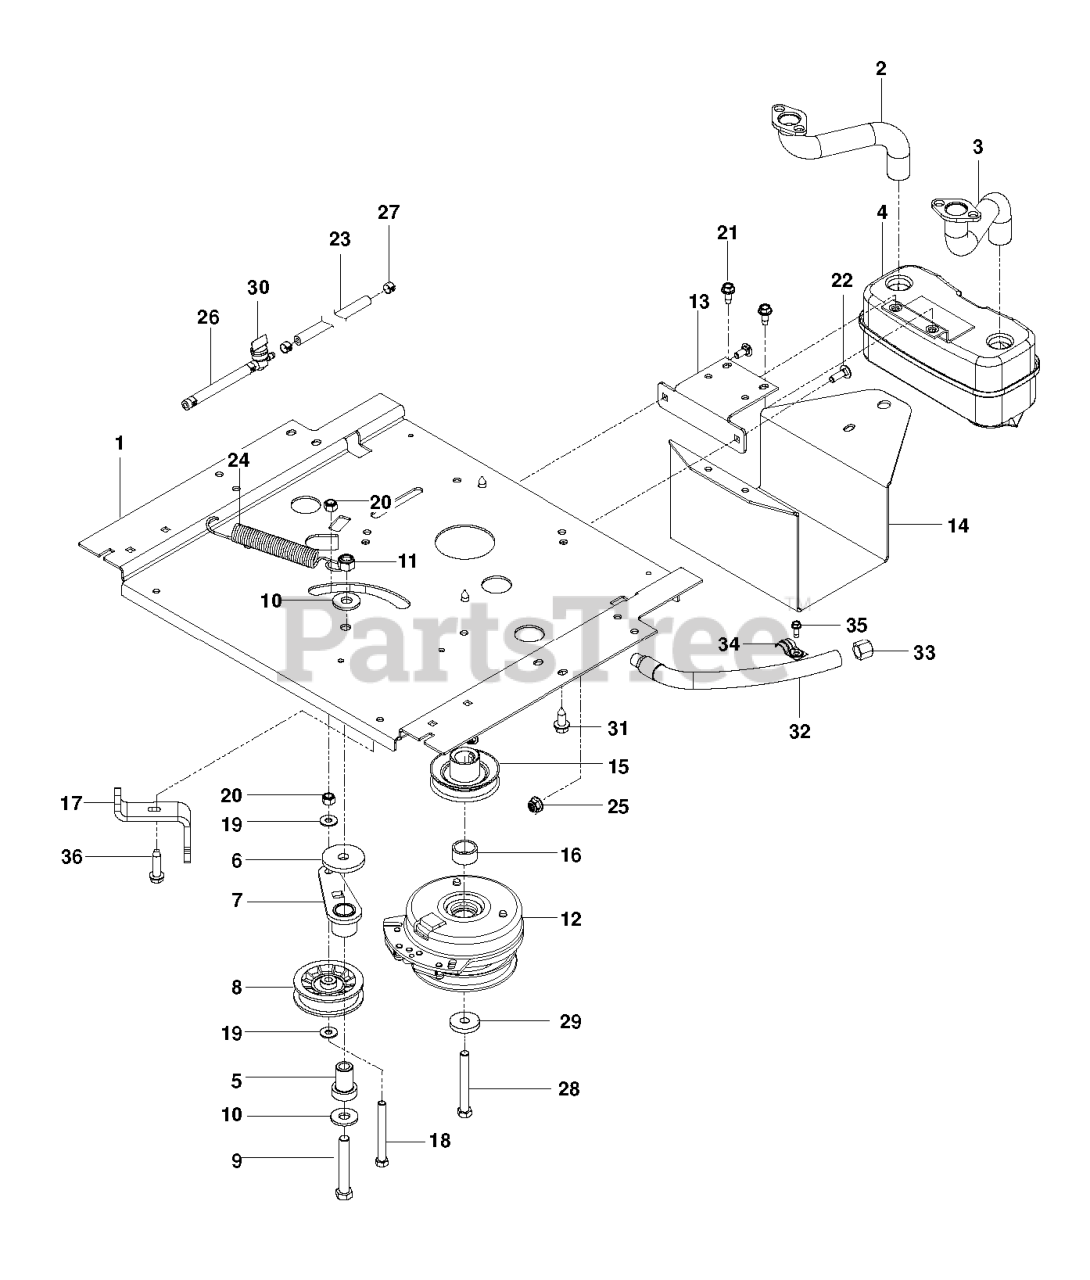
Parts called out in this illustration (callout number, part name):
1	PLATE, ENGINE WIDE, BLACK
2	RP.EXHAUST.TUBE.LH.BS/TWIN
3	EXHAUST.TUBE.RH.BS/TWIN
4	MUFFLER ASM TWIN
5	IDLER SPINDLE
6	HEAVY WASHER
7	RP.IDLER ARM WELDMENT
8	PULLEY, IDLER RAKE & ZTR
9	HCS 1/2C X 3 1/4
10	WASH USS FLAT 1/2
11	NUT 1/2-13 HEX NYLOC ZD
12	CLUTCH, 105 FT-LBS
13	BRACKET, MUFFLER, BLACK
14	GUARD, MUFFLER, BLACK
15	PULLEY, ENGINE
16	T & B SPACER
17	STOP, CLUTCH BLK
18	HCS 3/8-16X3 1/2 GR5
19	WASHER 5/16 FLAT
20	NUT 3/8-16 NYLOC
21	BOLT 5/16-18 X 3/4
22	BOLT 5/16C X 3/4" CARRIAGE
23	HOSE, FUEL .25 ID X 26"
24	SPRING, DECK DRIVE
25	5/16-18 NYLOC FLANGE NUT
26	FUEL LINE 5"
27	HOSE CLAMP
28	HCS 7/16-20X3-1/2 GR 5 ZN
29	CLUTCH, WASHER
30	FUEL VALVE
31	HHFS 3/8-16 X 1.0 THD FORMING
32	OIL DRAIN HOSE
35	SCREW 1/4 X 5/8
36	BOLT 3/8-16 X 1 1/2 ZINC CLEAR
